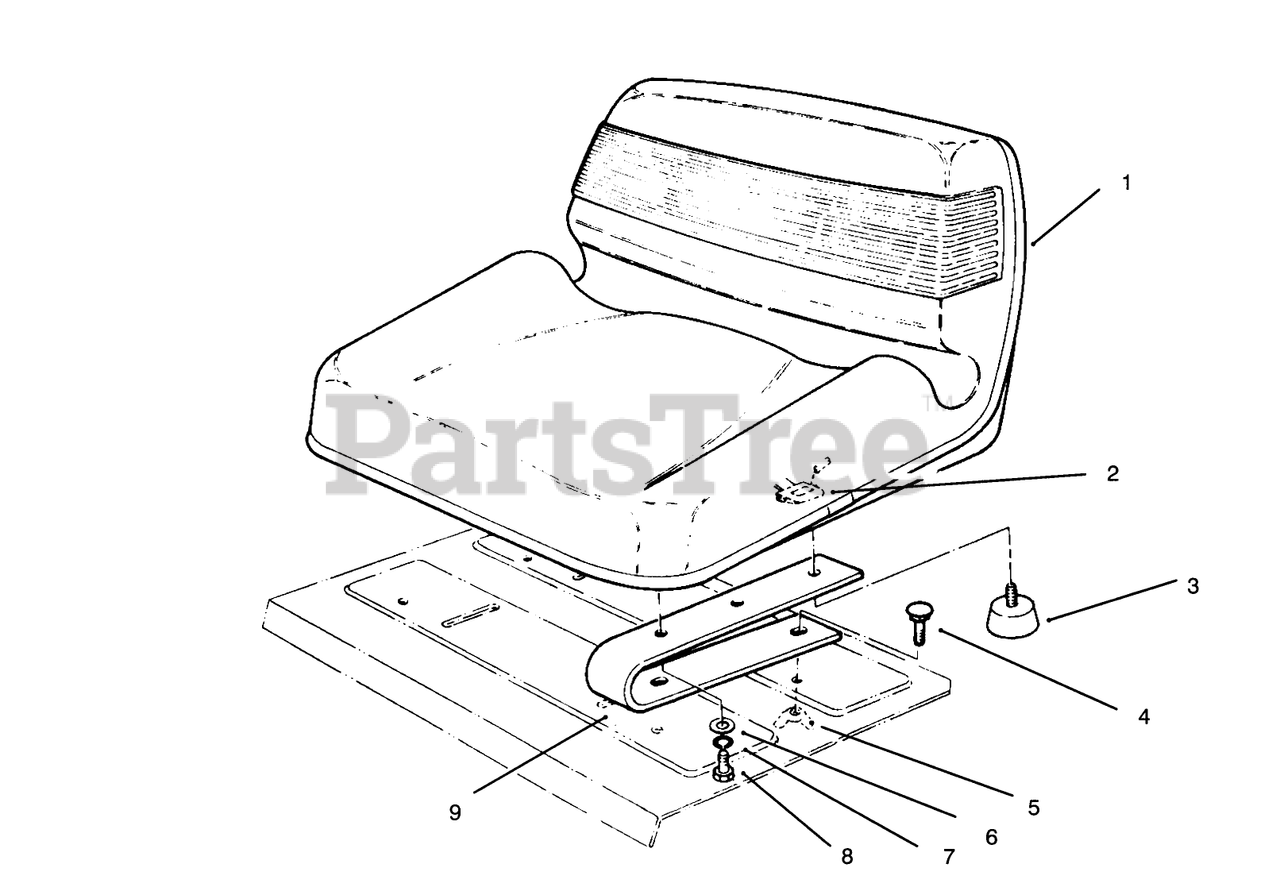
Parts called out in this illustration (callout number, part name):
1	Seat
2	SWITCH-SEAT
3	RUBBER BUMPER
4	SCREW-CARR
5	NUT-WING, LOCK
6	WASHER-PLAIN
7	10-24 X 3/4 FIL HD MS
8	SCREW-HH
9	Spring Seat
